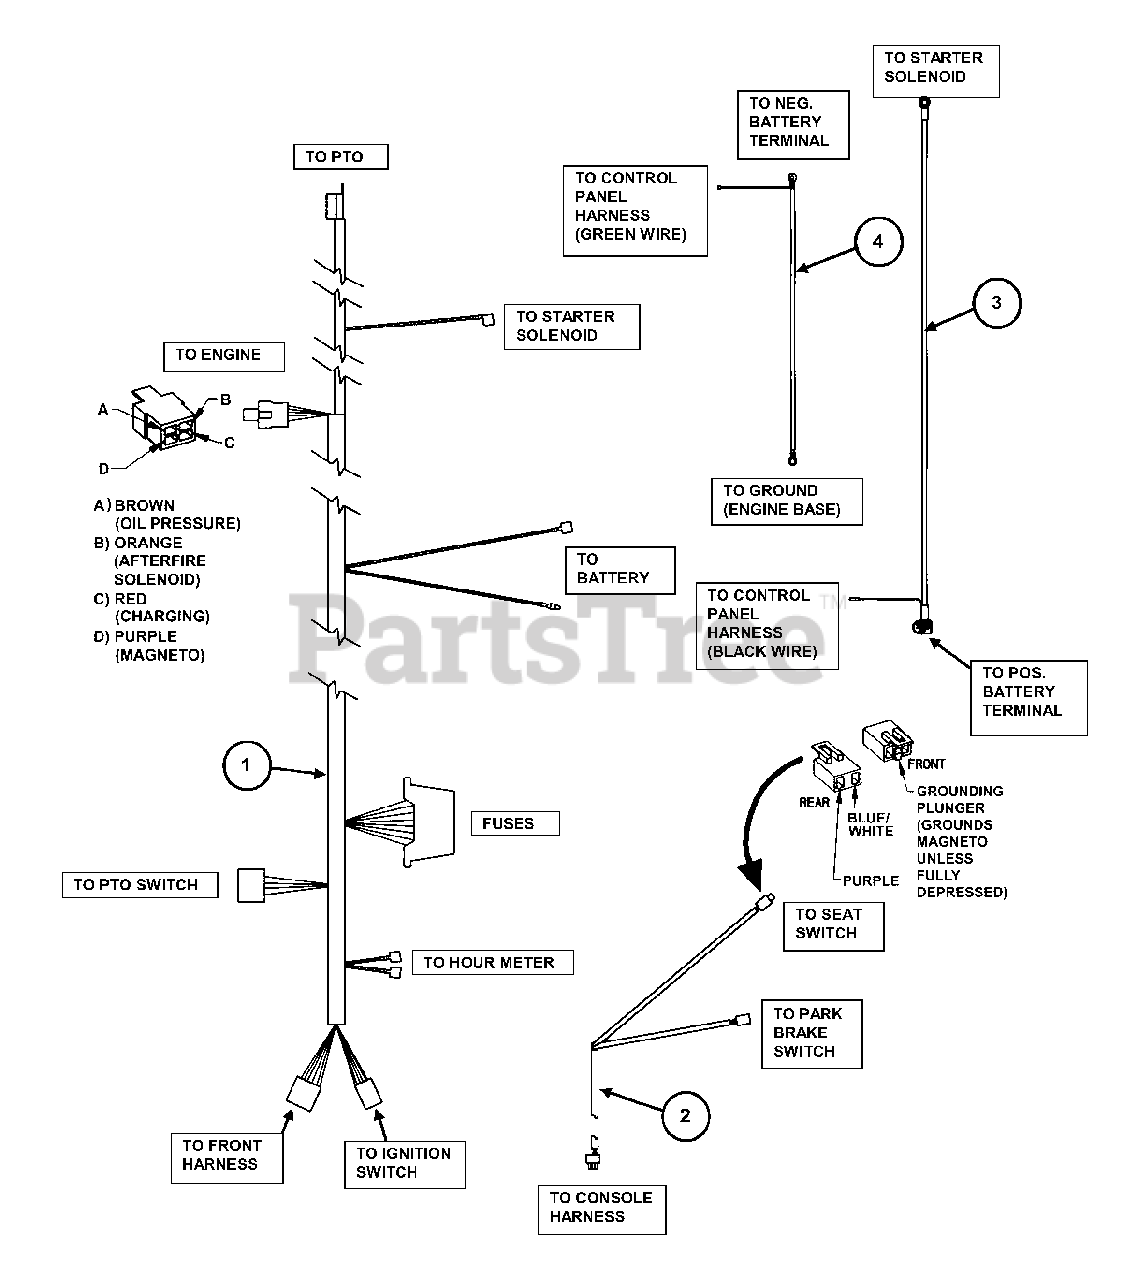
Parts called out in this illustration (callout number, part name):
1	HARNESS, Control Panel
2	HARNESS, Front
3	CABLE, Battery- Positive (6 Ga., 47")
4	CABLE, Battery- Negative (6 Ga., 38")
